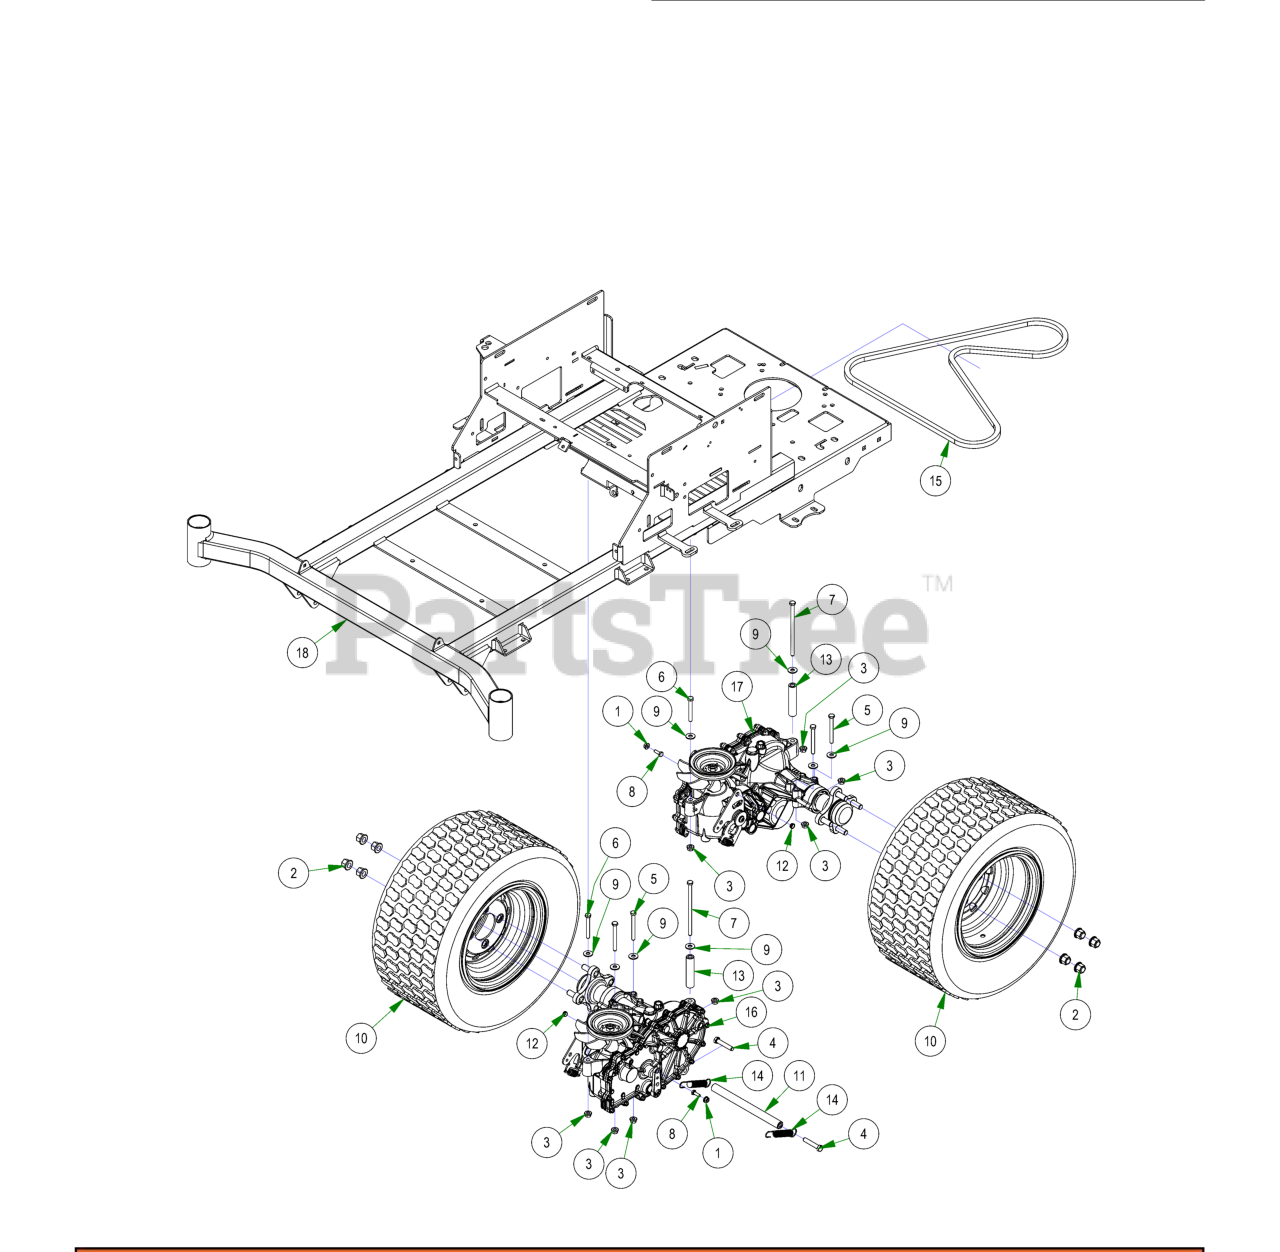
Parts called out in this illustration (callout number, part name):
1	1/4-20 NYL INSERT FLANGE LOCKNUT ZINC
2	Acorn Lug Nut
3	5/16-18 NYLON INSERT FLANGE LOCKNUT ZINC
4	3/8-16 X 2 HEX CAP SCREW (GR.5) ZINC
5	5/16-18 X 3 HEX CAP SCREW (GR.5) ZINC
6	5/16-18 X 2-1/2 HEX CAP SCREW (GR.5) ZINC
7	5/16-18 X 6 HEX CAP SCREW (GR.5) ZINC
8	1/4-20 X 3/4 HEX CAP SCREW (GR.5) ZINC
9	5/16 USS FLAT WASHER (7/8 OD) ZINC
10	20x12x10 Rear Tire & Black Wheel Assembly
11	2017 Transaxle Spacer-ZT
12	Drive Arm Transaxle Spacer
13	2017 Transaxle Spacer
14	Brake Return Spring
16	2021 RH 2800 Transaxle
17	2021 LH 2800 Transaxle
18	2024 MZ-Avenger 54-60 Frame
